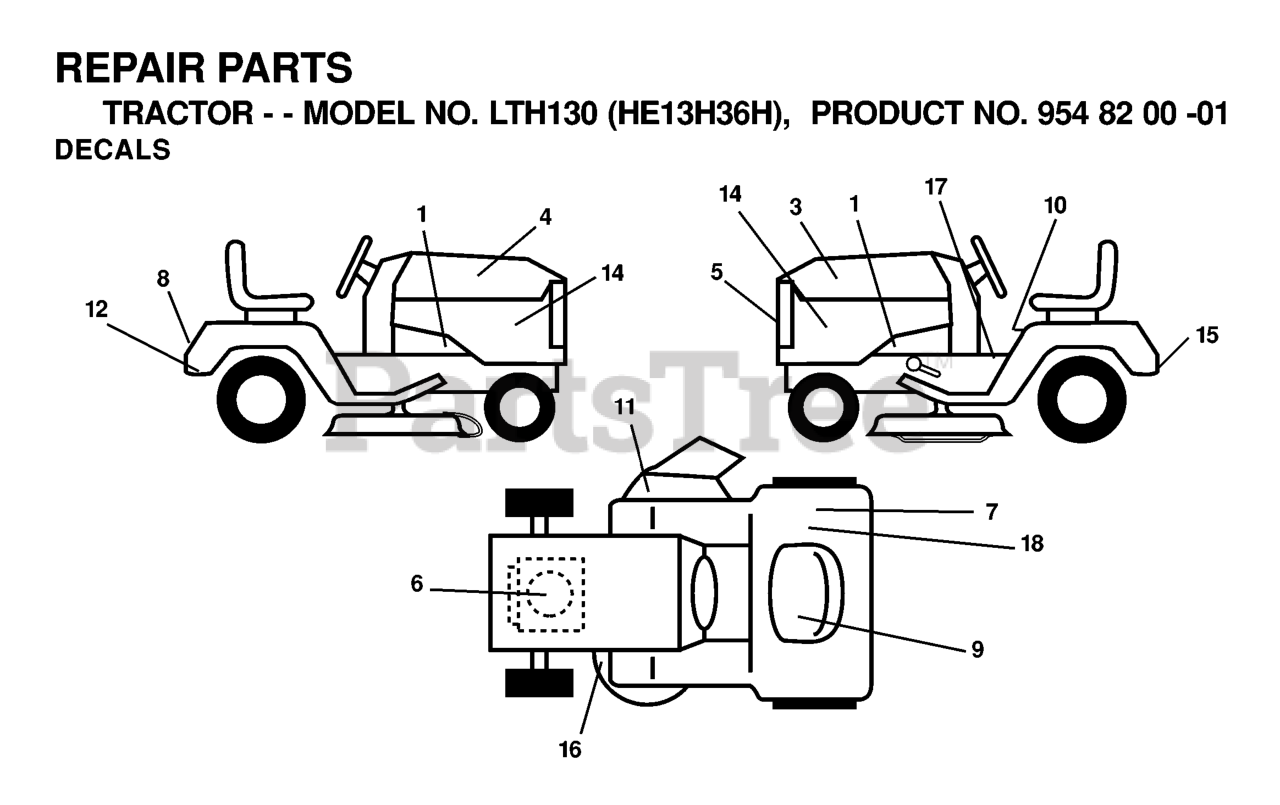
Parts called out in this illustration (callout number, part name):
5	DECAL.GRILLE.HUSQ
6	DECAL HP ENGINE
7	DECAL CERTIFICATION
8	DECAL FENDER HUSQ
9	DECAL BTRY SYMBOLS
10	DECAL READ OWNER'S MAN SYMS
11	DECAL MOWER CUT/FINGER
14	DECAL PNL SIDE
17	Decal, Brake/Clutch Symbols
18	DECAL EUROPE STANDARD CE
